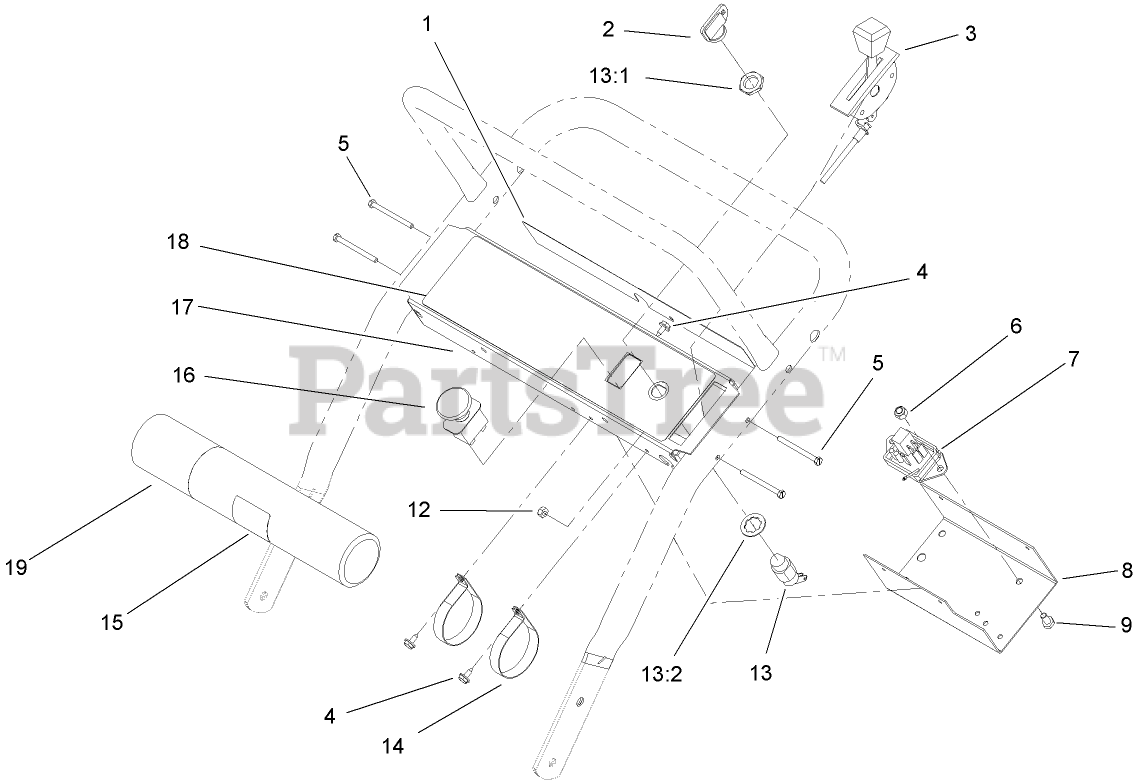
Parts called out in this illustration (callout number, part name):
1	DECAL-DANGER
2	KEY-IGNITION
3	CONTROL-THROTTLE
4	SCREW-HWHTF
5	SCREW-SHH
6	NUT-LOCK, NI
7	MODULE-DELAY
8	PANEL-BOTTOM
9	SCREW-HH
12	NUT-LOCK, NI
13	SWITCH-ON / OFF
13:1	NUT-HH
13:2	WASHER-TOOTH, INTERNAL
14	CLAMP-R
15	TUBE-MANUAL
16	SWITCH-PTO
17	PANEL-CONTROL
18	DECAL-CONTROL PANEL
19	CAP-HOUSING
